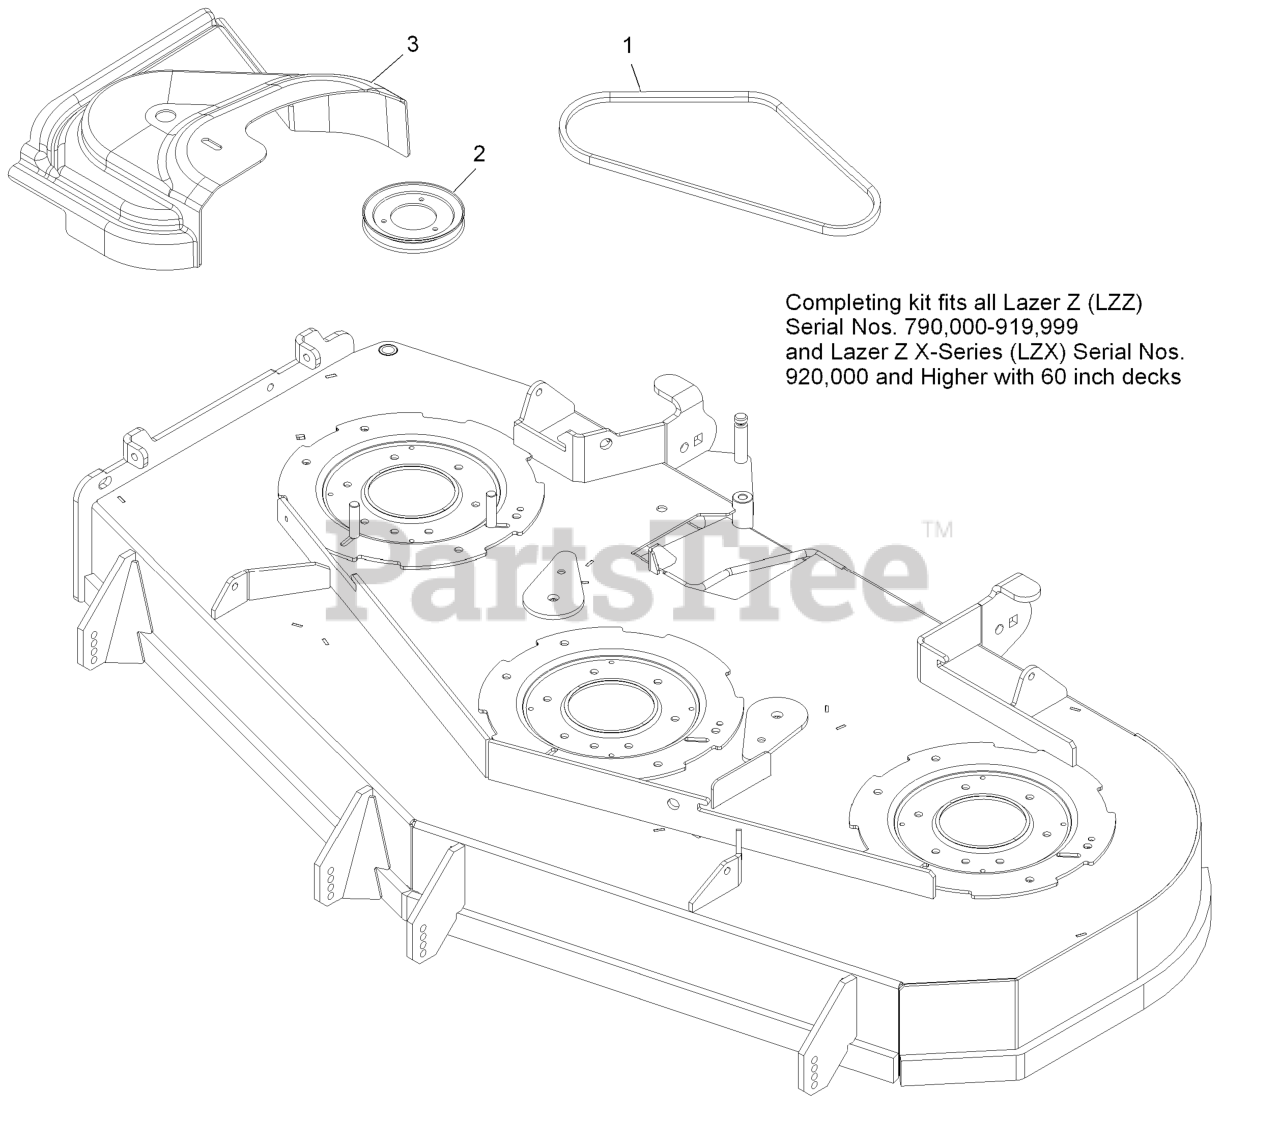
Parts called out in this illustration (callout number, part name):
1	Belt, Blower Drive 60
2	Sheave,Drive Lzuv 606
3	Cover,Belt Uv 60
